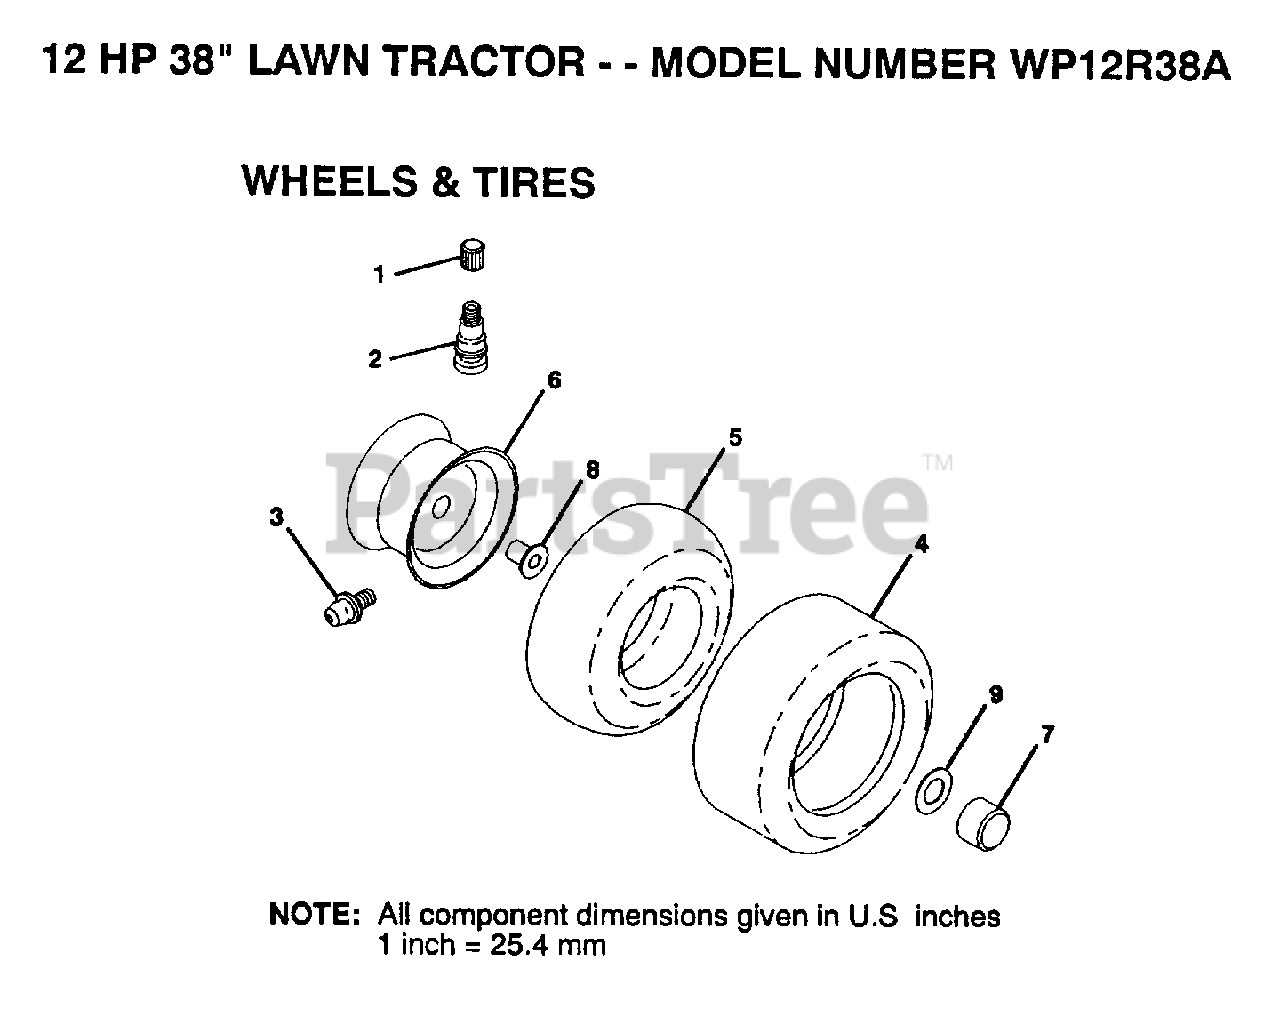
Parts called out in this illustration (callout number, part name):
1	VALVE CAP
2	VALVE STEM LT
3	FITTING LT
5	TUBE.5.3/4.5/6
7	HUB CAP
8	"FLANGE, BEARING"
9	WASHER
